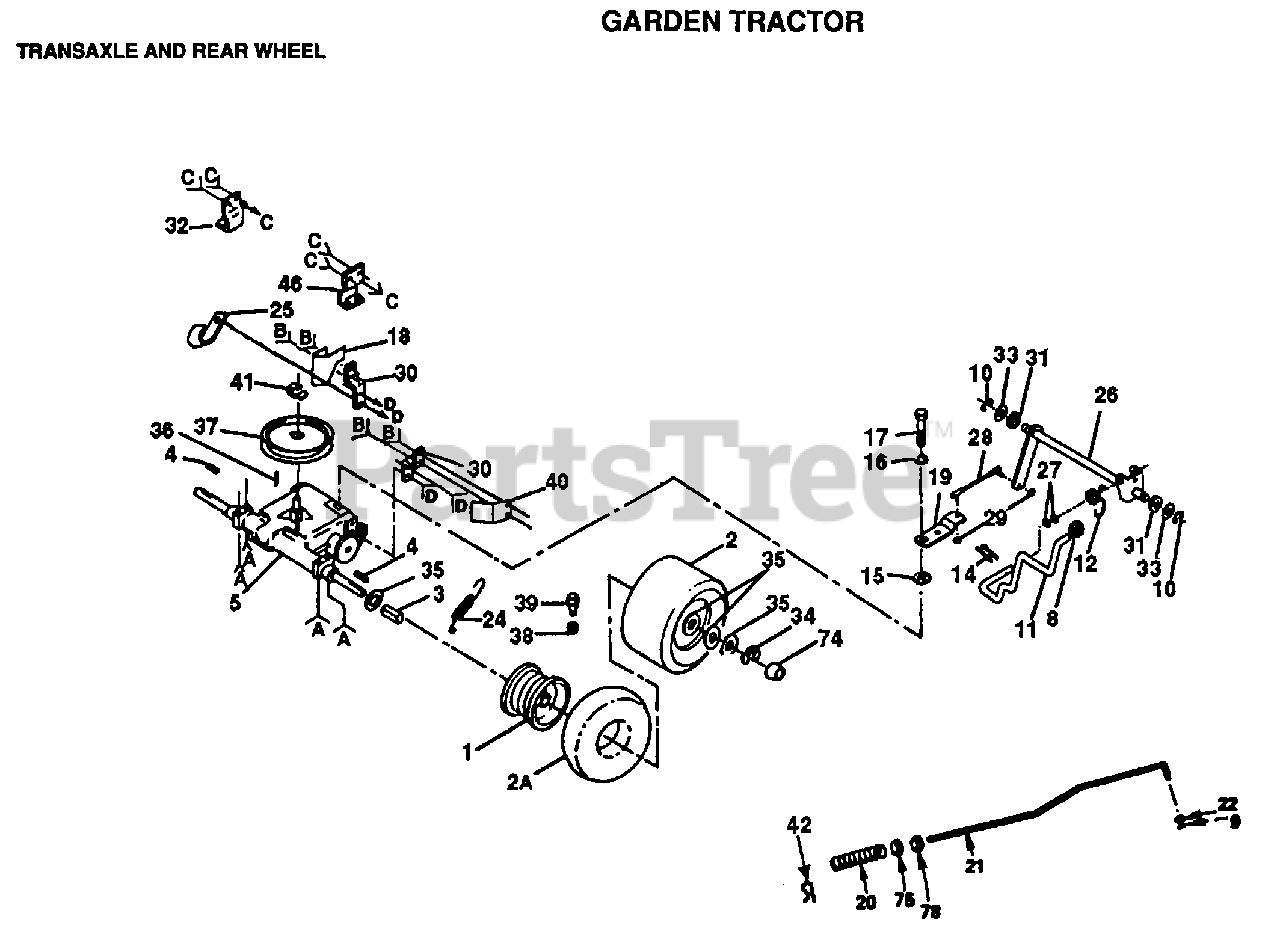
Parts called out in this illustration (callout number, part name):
2A	TUBE.23X8/10-12
3	SPACER HYT
4	SQ KEY STD
8	KNOB T (1/2-HOLE)
9	COTTER PIN
10	KLIP RING
12	"SPRING,TORSION"
14	PIN COTTER 1/8
15	WASH-SHFT PLT LT
16	WASHER PM
18	KEEPER BELT LH
19	"ARM,SHIFT"
20	"SPRING,ROD BRAKE"
21	ROD BRAKE
22	WASHER
25	CLIP T
26	"SHAFT,SHIFTER"
27	WASHER
28	"ROD,TIE "
29	NUT 1/4-28
30	STRAP TORQUE
31	BUSHING
32	BRKT TRANS LH
33	WASHER D
34	E RING HYT
35	WASHER
37	PULLEY TRANSAXLE
38	VALVE CAP
39	VALVE STEM LT
40	"KEEPER,BELT RH"
41	RING
42	RETAINER M
46	BRKT TRANS RH
74	HUB CAP
75	NUT
78	NUT
